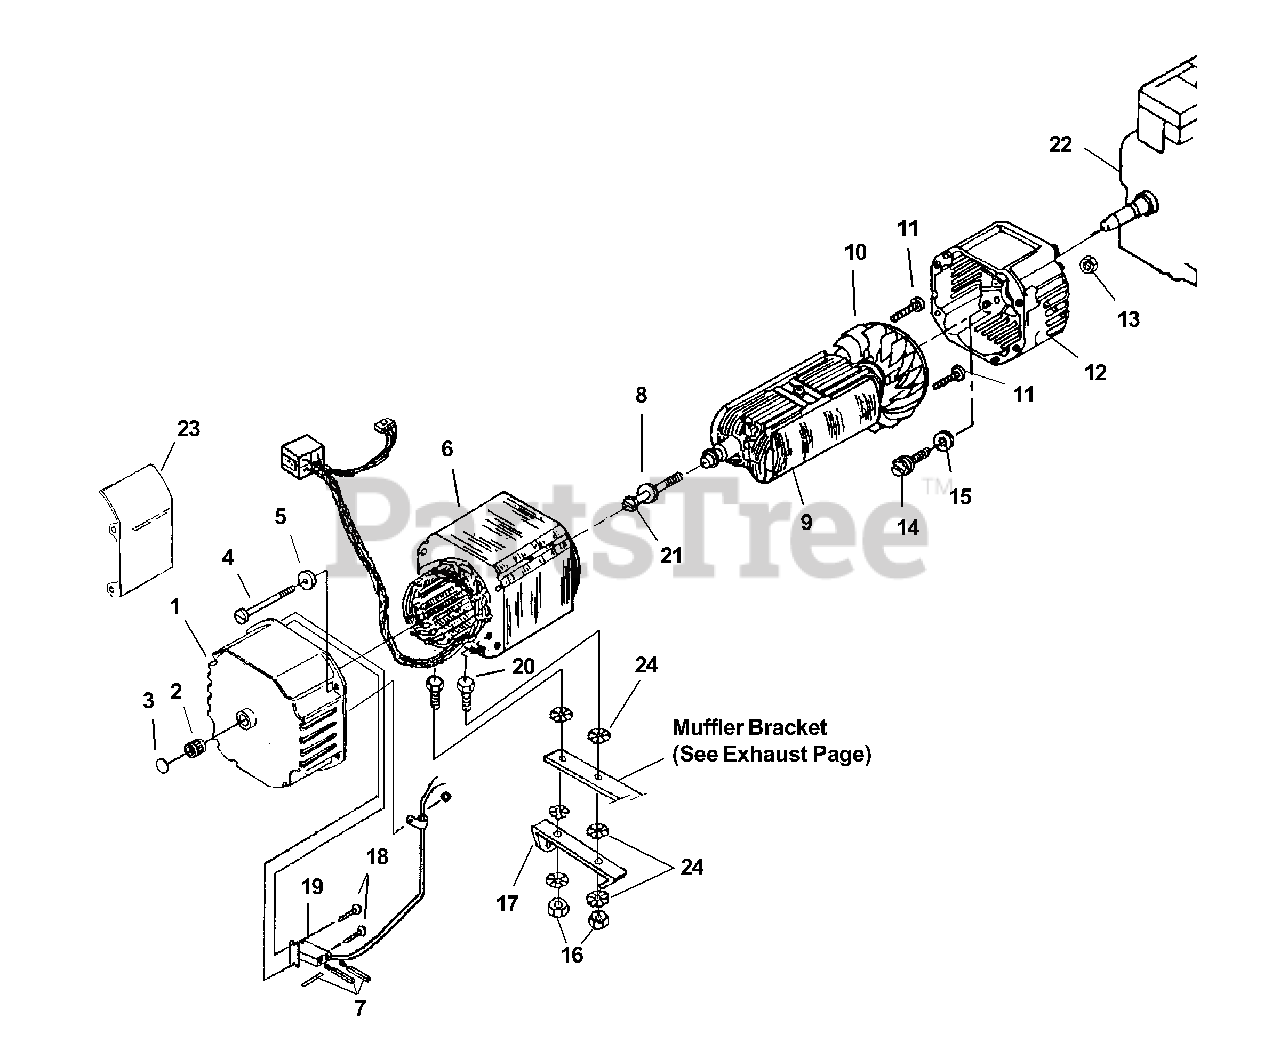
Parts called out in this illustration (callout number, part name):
1	Complete Brush Head
2	Bearing-Needle
3	Plug-Expansion
4	Bolt-Stator
5	Washer-Flat (1/4")
6	(Stator & Harness)
7	Brush & Retainer Kit
8	Washer-Lock (5/16")
10	Fan-Generator
11	Screw-Pan Hd. (6-19 X 3/4")
12	End Bell
13	Nut-Hex (1/4-20)
14	Screw-Hex Hd. (3/8-16 x .875)
15	Washer-Lock
16	Nut-Hex (5/16-18)
17	Bracket-Generator Support
18	Screw-Plastite (6/19 X 3/4")
19	Brush Holder
20	Screw- Hex Hd. (5/16-18 X 1")
21	Bolt-Rotor
22	Engine (EH36)
23	Brush Shield
24	Washer-Lock
